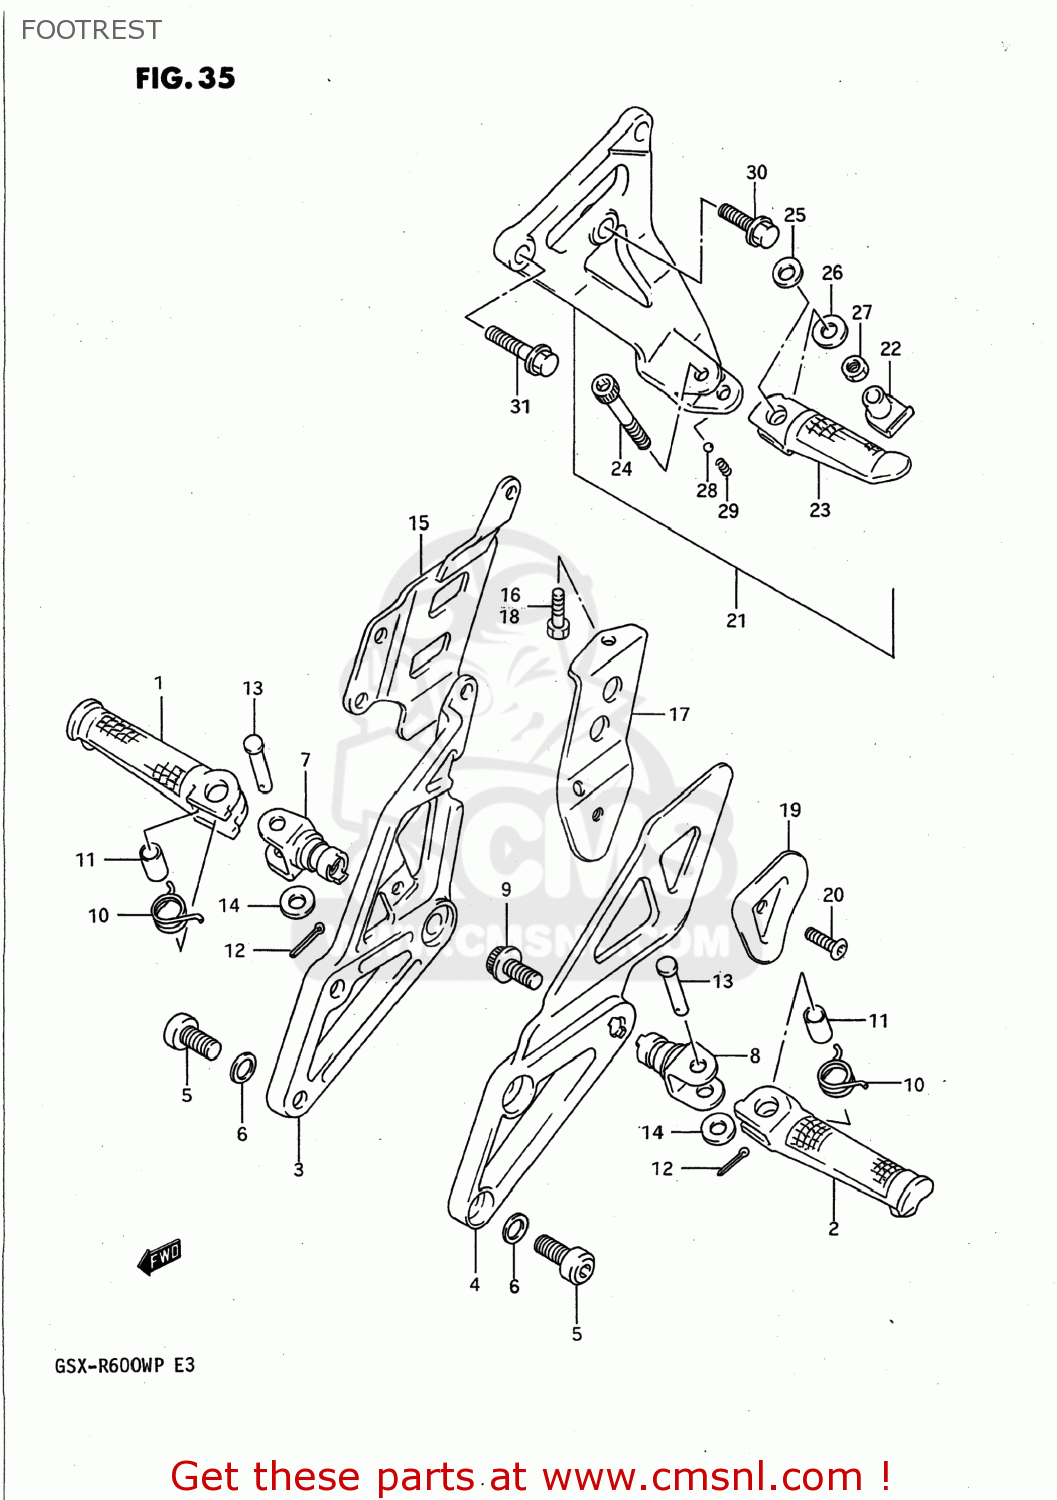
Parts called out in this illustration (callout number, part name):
1	BAR,FOOTREST,R
2	BAR,FOOTREST,L
3	BAR,FRONT FOOTREST
4	BRACKET,FRONT FOOTREST
5	BOLT,FOOTREST BRACKET
6	WASHER
7	HOLDER,FOOTREST,RIGHT
8	HOLDER,FOOTREST,L
9	BOLT(10X24)
10	SPRING
11	SPACER(8.1X12X22)
12	PIN 20X15
13	PIN
14	WASHER(8.5X18X1)
15	GUARD,FRONT FOOTREST,RIGHT
16	BOLT
17	REINFORCEMENT,FOOTREST,L
18	BOLT
19	PLATE,REINFORCEMENT,L
20	SCREW(6X12)
21	FOOTREST ASSY,PILLION,R
22	BOSS,PILLION FOOTREST,L
23	BAR,PILLION FOOTREST R
24	BOLT ,8X50
25	WASHER(8.5X18X1)
26	WASHER
27	NUT
28	BALL
29	SPRING
30	BOLT
31	BOLT 8X30
